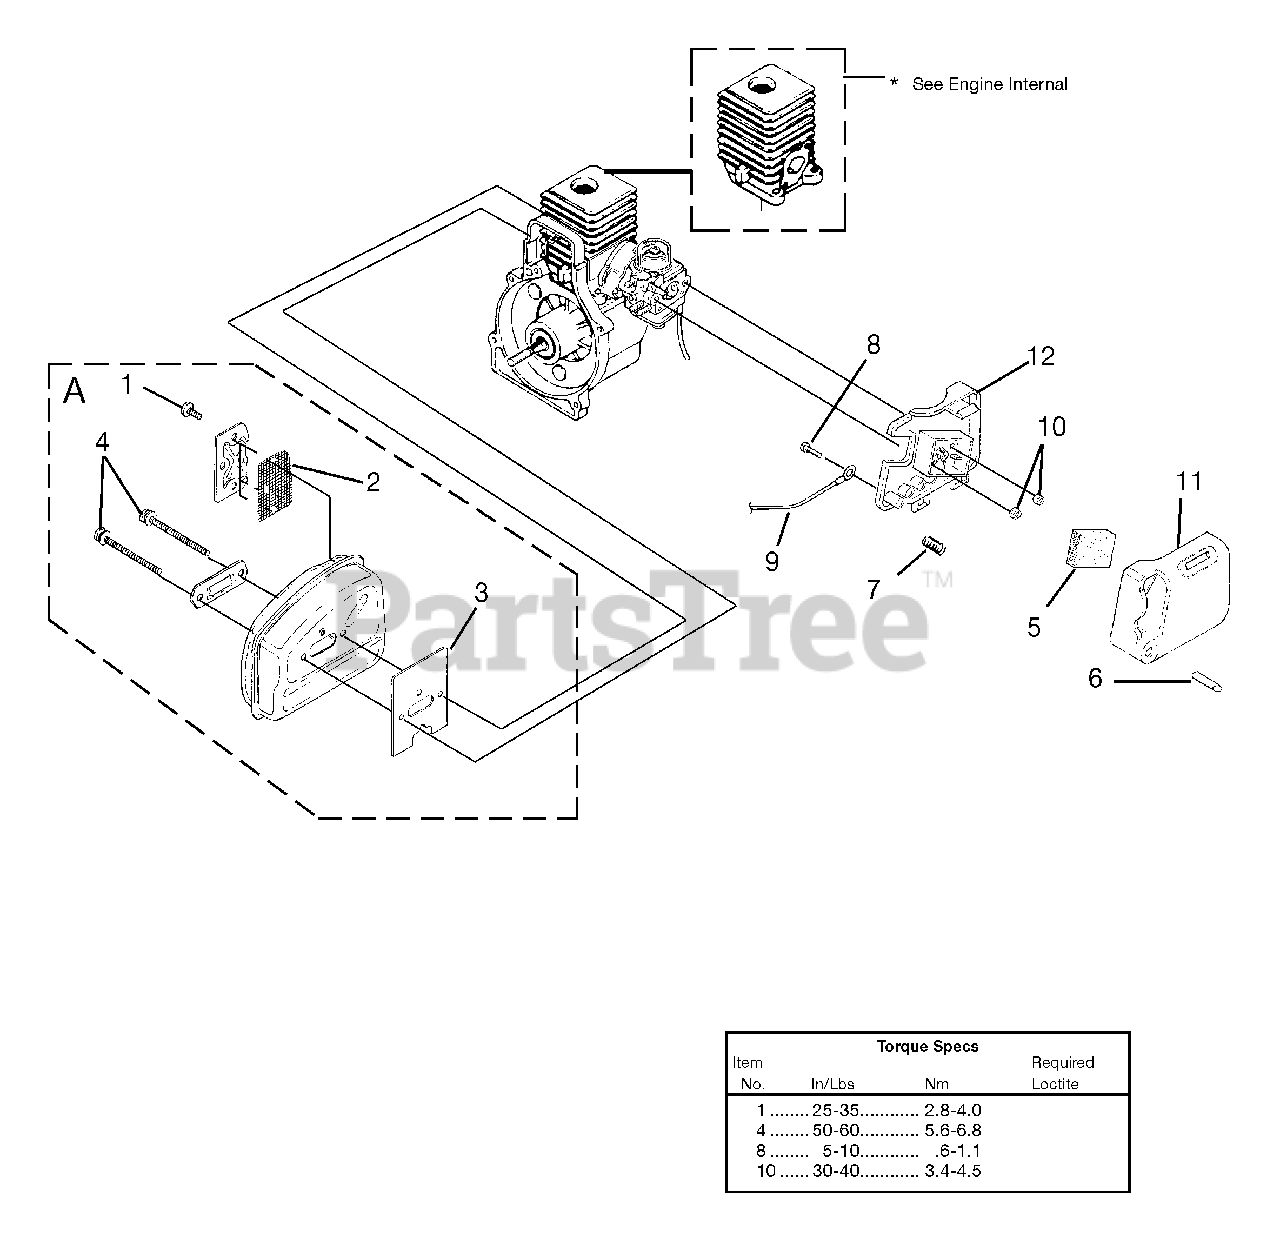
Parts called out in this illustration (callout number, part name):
1	SCREW-Taptite - (8-32 X 3/8")
2	SCREEN-Spark
3	GASKET-Muffler
4	SCREW-Truss Hd. - (10-24 X 2.188)
5	FILTER-Air
6	BUTTON-Switch
7	SPRING-Compression
8	SCREW-Thread Form (6-19 x 1/2")
9	LEAD-Electrical
10	NUT-Hex (10-24)
11	COVER-Air Box
12	BOX-Air Filter
A	MUFFLER ASSY.
